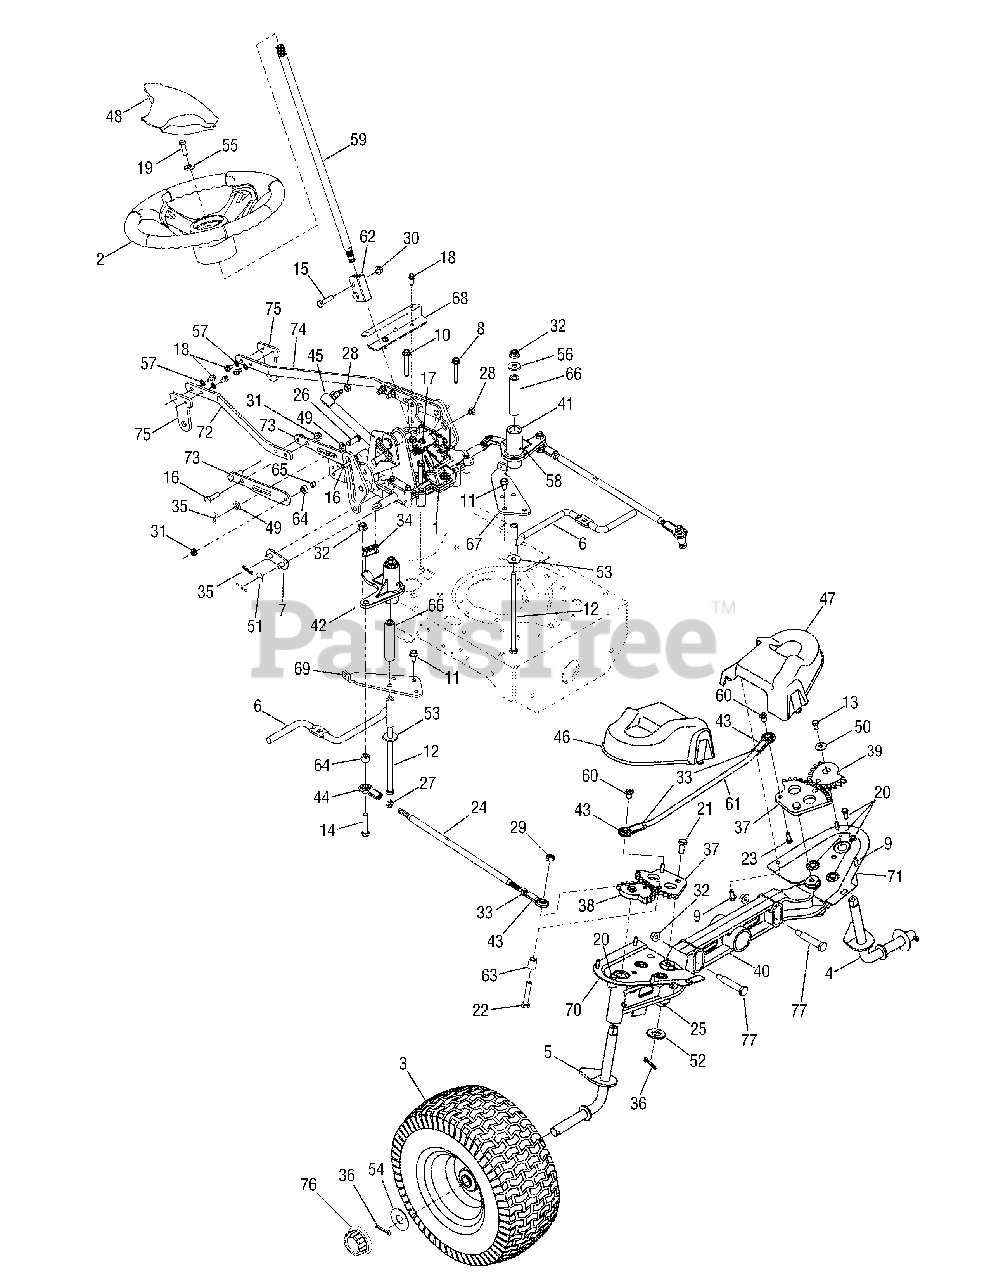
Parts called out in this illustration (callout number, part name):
1	Steering Assembly, Steering/Hydro
1	Kit, Replacment Steering Gear Box
2	Steering Wheel Assembly
4	Axle Assembly, LH
5	Axle Assembly, RH
6	Rod, Fender Support
7	Link, Steering Box/Hydro
8	Screw, Hex Wash Hd. Tapp, 5/16-18 x 2.0
9	Screw, Hex Wash Hd. Hi/Lo, 1/4-15 x .5
10	Screw, Hex Wash Hd. Tapp, 5/16-18 x 2.25
11	Screw, Hex Wash Hd. Tapp, 5/16-18 x .75
12	Screw, Hex Cap, 3/8-16 x 7.25 Gr5
13	Screw, Hex Cap Lock, 1/4-28 x .625 Gr5
14	Screw, Hex Cap, 3/8-16 x 1.5 Gr5
15	Screw, Hex Cap, 5/16-18 x 1.25 Gr5
16	Screw, Hex Cap, 1/4-20 x 1.0 Gr5
17	Screw, Hex Wash Hd. Tapp, 1/4-20 x .5
18	Screw, Hex Wash Hd. Tapp, 1/4-20 x .75
19	Screw, Hex Wash Hd. Tapp, 5/16-18 x .875
20	Screw, Hex Cap, 1/4-20 x .75 Gr5
21	Screw, Hex Cap Lock, 3/8-16 x .75 Gr5
22	Screw, Hex Cap, 3/8-16 x 2.0 Gr5
23	Screw, Hex Cap Lock, 1/4-20 x .75 Gr5
24	Link, Drag
25	Shaft, Steering Pivot Gear
26	Pin, Clevis, .375 x .969 HT
27	Nut, Jam, 3/8-24 LH Thrd
28	Nut, Hex Lock, M8 x 1.25 Gr9
29	Nut, Hex Lock, 3/8-16
30	Nut, Hex Insert Flange Lock, 5/16-18 GrF
31	Nut, Hex Insert Flange Lock, 1/4-20 GrF
32	Nut, Hex Insert Flange Lock, 3/16-16 GrF
33	Nut, Hex Jam, 3/8-24 Gr2
34	Link, Connnecting
35	Pin, Internal Cotter
36	Pin, Cotter, 5/32 x 1.25
37	Gear, Spur, 12T
38	Gear, Spur, RH 13T
39	Gear, Spur, LH 13T
40	Axle, Pivot Bar
41	Arm, Steering, LH
42	Arm, Steering, RH
43	End, Ball Joint Rod
44	End, Ball Joint Rod, LH Thrd.
45	Cylinder, Damper
46	Cover, Steering Gear, RH
47	Cover, Steering Gear, LH
48	Cover, Steering Wheel
49	Washer, Flat, .375 x .738.063
50	Washer, Bell, .265 x .75 x .062
51	Washer, Sping, .39 x .75 x .010
52	Washer, Flat, .76 x 1.5 x .12
53	Washer, Bell, .396 x 1.14 x .095
54	Washer, Flat, .755 x 1.92 x .060
55	Washer, Flat, .406 x .875 x .105
56	Washer, Flat, .406 x 1.0 x .105
57	Washer, External Lock, 1/4
58	Fitting, Grease
59	Shaft, Steering, .625 x 17.281
60	Nut, Shoulder, .375 x .5
61	Rod, 3/8-24 x 14.4 Lg
62	Block, Steering Shaft
63	Spacer, .385 x .63 x .75
64	Spacer, .380 x .625 x .265
65	Spacer, .26 x .372 x .33
66	Spacer, .385 x .75 x 3.47
67	Bracket, Steering Support, LH
68	Bracket, Steering Support, Upper
69	Bracket, Steering Support, RH
70	Plate, Base Cover, RH
71	Plate, Base Cover, LH
72	Link, Steering/Hydro RH
73	Bracket, Hydro/Steering Adjustment
74	Link, Steering/Hydro LH
75	Bracket, Steering Link
77	Bolt, Shoulder, .5 x 2.23:3/8-16
78	Screw, Hex Cap, 1/4-20 x 1.0 Gr5
79	Nut, Hex Insert Flange Lock, 1/4-20
